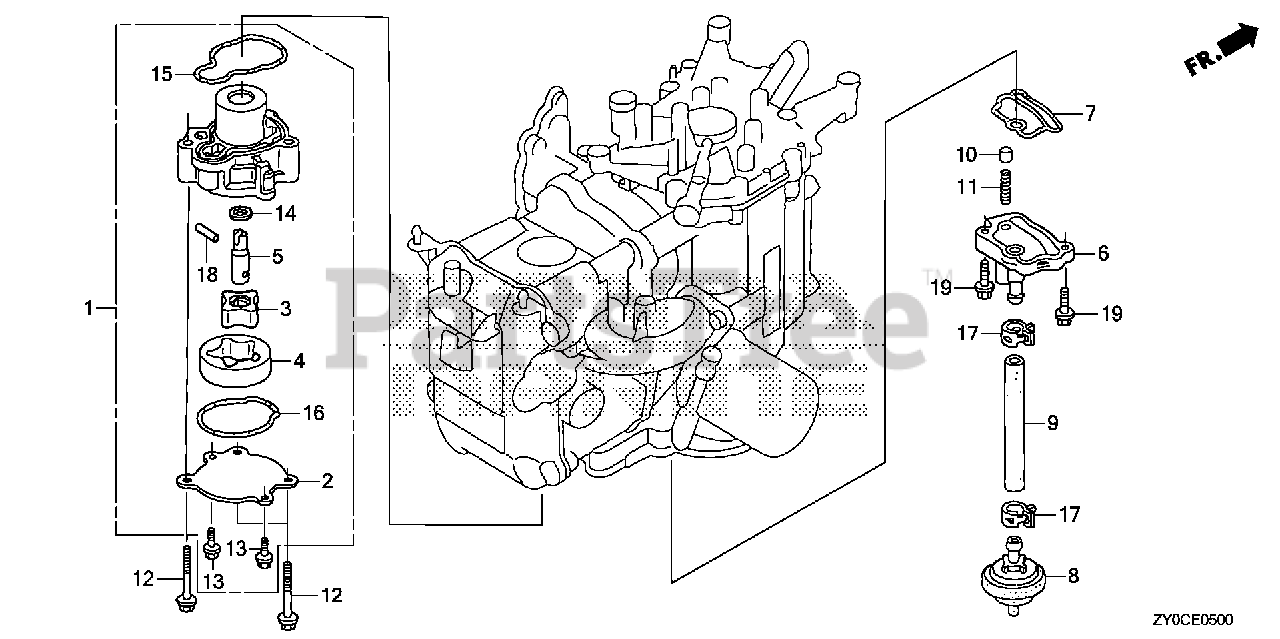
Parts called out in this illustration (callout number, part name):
1	PUMP ASSY., OIL
2	COVER, OIL PUMP
3	ROTOR (INNER)
4	ROTOR (OUTER)
5	SHAFT, OIL PUMP
6	FLANGE, OIL STRAINER
7	O-RING, OIL STRAINER FLANGE
8	STRAINER, OIL
10	VALVE, CHECK
11	SPRING, CHECK VALVE
12	BOLT, FLANGE (6X35)
13	BOLT, FLANGE (5X12) (CT200)
14	WASHER, THRUST (11MM)
15	O-RING, OIL PUMP
16	O-RING, PUMP COVER
17	CLAMP, TUBE (D17)
18	ROLLER (4X15.8)
19	BOLT, FLANGE (6X22)
